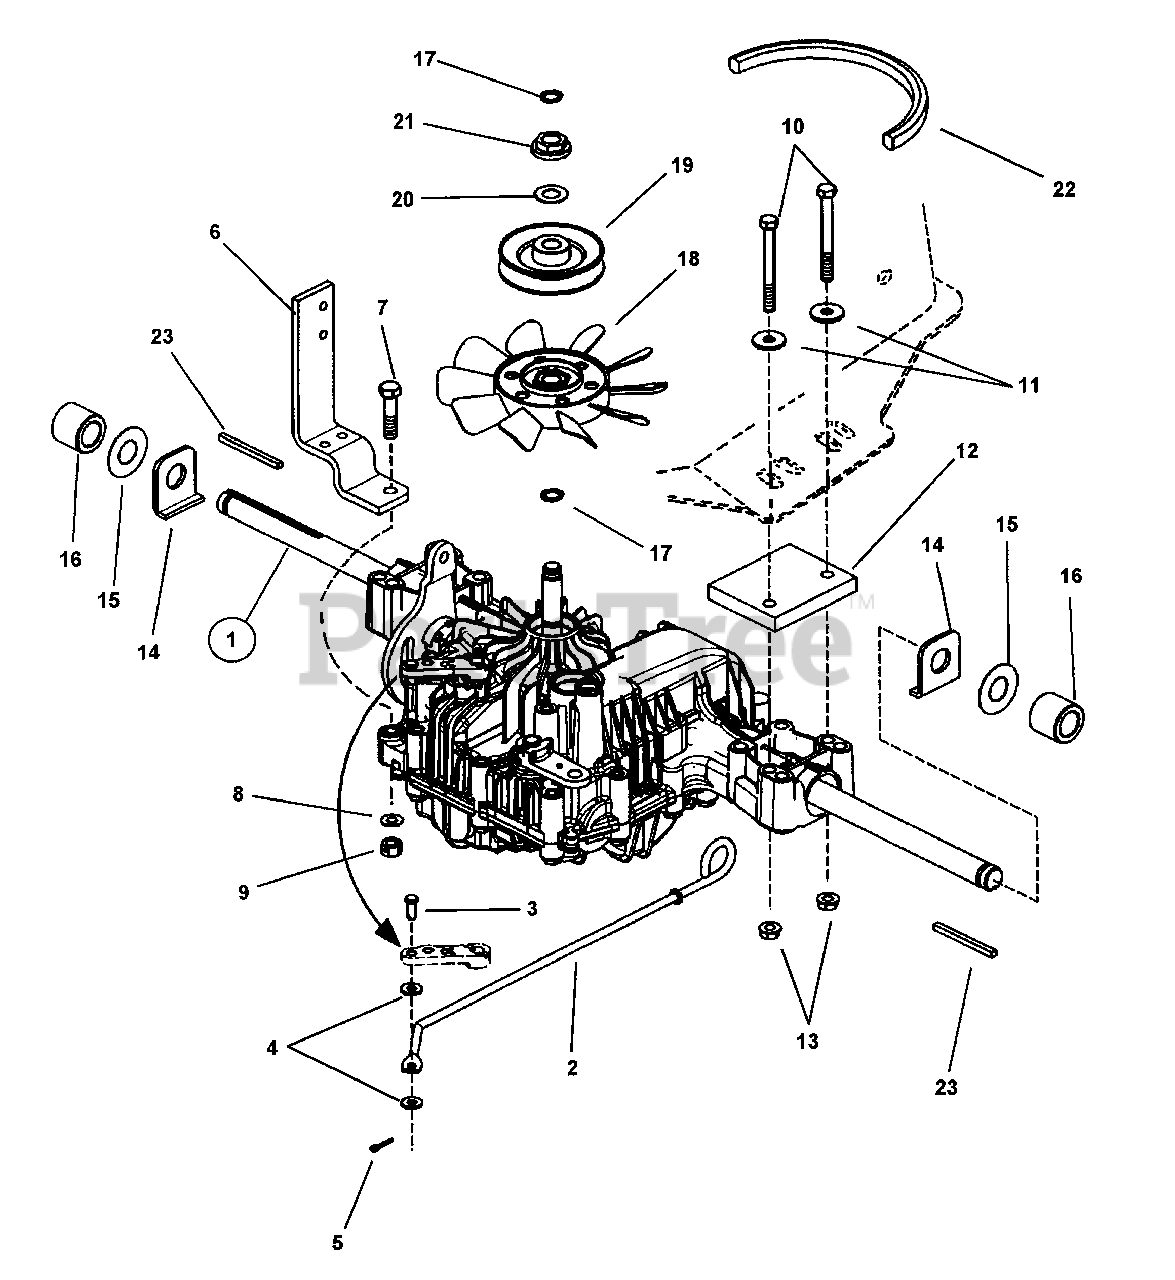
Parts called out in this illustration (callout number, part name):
1	ASSEMBLY, Transaxle, K-46 Tuff Torq
2	ROD, Roll Release
3	PIN, Clevis 1/4" x 5/8"
4	WASHER, 1/4 x 5/8 x 1/16" Flat
5	PIN, 3/32" x 1/2" Cotter
6	BRACKET, Torque
7	SCREW, 3/8-16 x 1-1/2" Hex Head Cap, Grade 5
8	WASHER, 5/16 x 11/16 x 1/16", Grade 5
9	NUT, 3/8-16 Hex Center Lock
10	SCREW, 5/16-18 x 3-1/4" Hex Head Cap, Grade 5
11	WASHER, 5/16" Flat
12	SPACER, Hydro Axle - K46
13	NUT, 5/16-18 Hex Flange Lock Grade 5
14	WASHER, Axle
15	WASHER, Thrust
16	SPACER, Axle
17	RING, E 15
18	FAN
19	PULLEY, 4" Diameter
20	WASHER, Wave
21	SPACER
22	BELT, Traction Drive
23	KEY, 3/16" Square x 2-3/16" long
